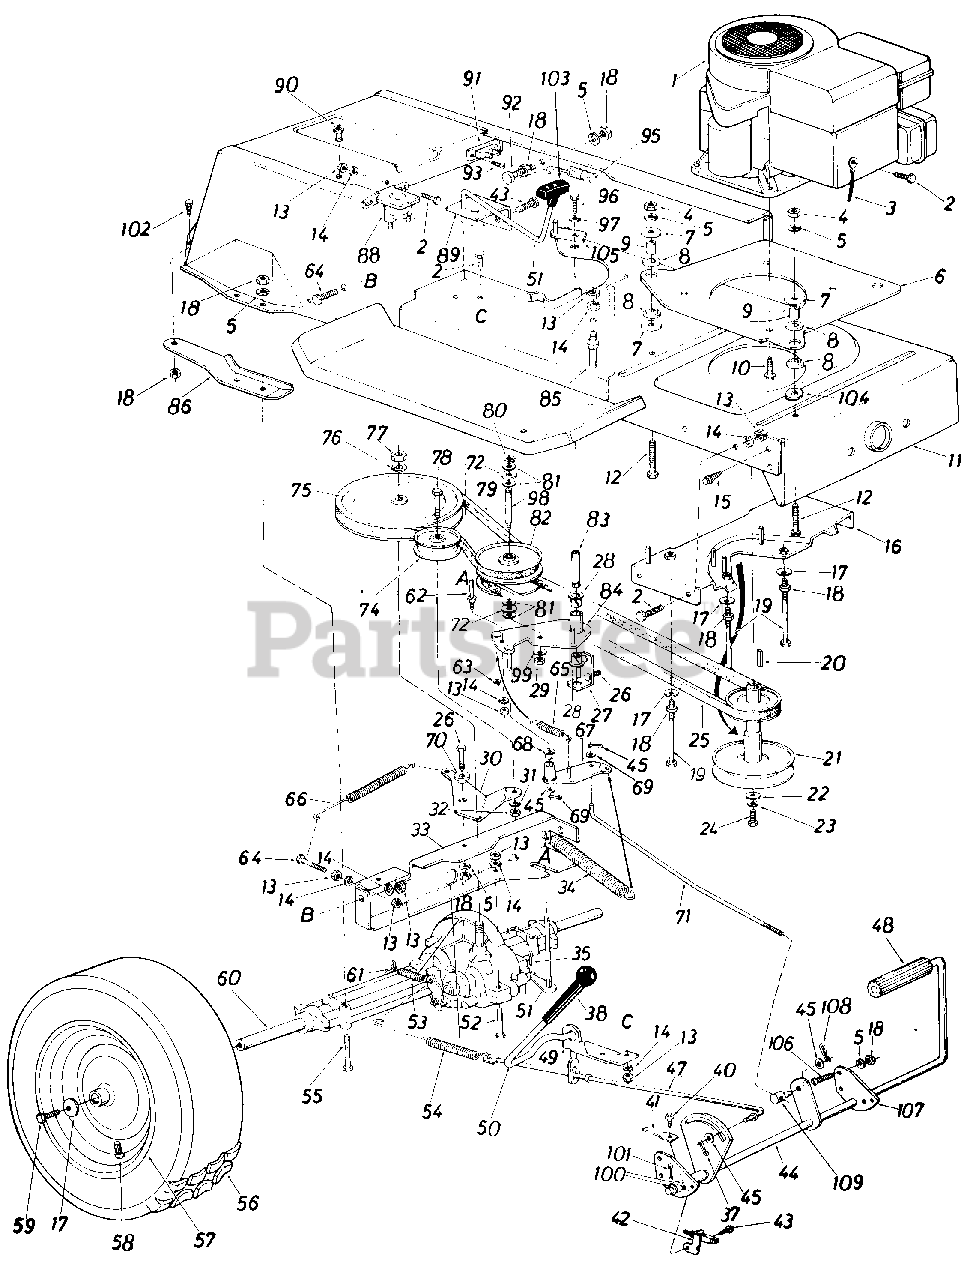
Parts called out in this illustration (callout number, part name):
2	Hex Bolt 1/4-20 x .62" Lg.*
3	Electric Ground Wire
4	Hex Nut 5/16-24 Thd.*
5	L-Wash. 5/16" I.D.*
6	Engine Mounting Plate
7	Fl-Wash. .320" I.D. x 1.25"
8	Engine Mounting Grommet
9	Spacer
10	Hex Bolt 3/8-16 x 1.25" Lg.
11	Lower Frame Ass'y.
12	Hex Bolt 5/16-24 x 1.25"*
13	Hex Nut 1/4-20 Thd.*
14	L-Wash. 1/4" I.D.*
15	Hex Wash Hd. AB-Tap Scr. 5116 x 75' Lg.
16	Belt Guard Brk't. Ass'y.
17	Bell-Wash. .345" I.D. x .88"
18	Hex Nut 5/16-18 Thd.*
19	Hex Bolt 5/16-18 x 4.00"*
20	Sq. Key 1/4" x 1/4" x 2.00"
21	Engine Pulley
22	Fl-Wash. 7/16" I.D. x 1.25"
23	L-Wash. 7/16" I.D.*
24	Hex Bolt 7/16-20 x 1.50" Lg.
25	Variable-Speed Belt .715 x 53" Lg.
26	Hex Bolt 5/16-18 x .75" Lg.*
27	Bearing Shaft Bracket
28	Flanged Nyliner Brg. 5/8" I.D. x .88" Lg.
29	Hex Nut 3/8-24 Thd.*
30	Idler Bracket
31	L-Wash. 3/8" I.D.*
32	Hex Nut 3/8-24 Thd.*
33	Transaxle Support Brk't.
34	Ext. Spring .99" O.D. x 6.7
35	Cotter Pin 1/8" Dia. x 1.0"*
37	Cotter Pin 3/32" Dia. x 1.0"*
38	Grip Black
40	Hex Wash. Hd. Self-Tap Scr. 1/4-20 x .50" Lg.
41	Switch Actuator
42	Safety Switch
43	Hex Wash. Hd. AB-Tap Scr. 1/4 x .62" Lg.
44	Clutch & Brake Pedal Ass'y.
45	Fl-Wash .
47	Brake Rod
48	Foot Pad
49	Brake Lever Bracket
50	Hill Holder Brake Handle
51	Shift Lever Ass'y.
52	Hex Bolt 1/4-28 x 1.75" Lg.*
53	Ext. Spring .38" O.D. x 2.5"
54	Ext. Spring .59" O.D. x 7.08"
55	Hex Bolt 5/16-18 x 2.50"*
56	Wheel Ass'y. Comp.
58	Air Valve
59	Hex Bolt 5/16-24 x .75" Lg.
60	Transaxle Complete
61	Brake Return Spring Anchor
62	Belt Guard Pin 1/4-20 Thd.
63	Cap Speed Nut 1/4" Dia.
65	Ext. Spring .50" Dia.
66	Ext. Spring .62"' O.D. x 6.12"
67	Variable Speed Torque Brk't. Ass'y.
68	Flanged Bearing
69	Cotter Pin 3132" Dia.
70	Shoulder Spacer .500" Dia. x .27" Lg.
71	Speed Control Link
72	Truss Bearing .56 Dia. x 1 .25 "
74	Fl-Idler Pulley 3.25" x 1.0"
75	11/16" "V"-Pulley 8.0" O.D. x .501" I.D.
76	L-Wash. 1/2" I.D.
77	Hex Jam Nut 1/2-20 Thd.
78	Hex Bolt 3/8-24 x 1.50" Lg.
79	Variable Speed Belt .715 x 44" Lg.
80	Snap Ring .56" Dia.
81	Fl-Wash.
82	Variable Speed Pulley Ass'y. 5" O.D.
83	Bearing Shaft
84	Variable Speed Brk't. Ass'y.
85	Belt Guard Pin 1/4" Dia. x 1.68" Lg.
86	Transaxle Support Brk't. R.H.
88	Solenoid
89	Shift Lever Bracket
90	Nyliner Brg. .375" Dia.
91	Circuit Breaker
92	Hex Bolt 5/16-18 x 1.25" Lg.
93	Truss Hd. Phil. Scr. #10 x 1/2" Lg.
95	Ext. Spring .99" O.D. x 11.0"
96	Hex Bolt 3/8-24 x .75n Lg.
97	Bell-Wash. .38" I.D. x .88n
98	Shaft .56" Dia. x 3.875" Lg.
99	Bell-Wash. .39" I.D. x 1.12"
100	Fl-Wash.
101	Cotter Pin
102	Hex Wash. Hd. Scr. 5/16-18 x .62 n Lg.
103	"T" Shif.t Knob
104	Fl-Wash. .32n l.D. x 1.25n
105	Belt Guard
106	Truss Mach. Scr. 5/16-18 x .75" Lg.
107	Pedal Brk't.
108	Hairpin Cotter 1/8" Dia.
109	Ferrule
